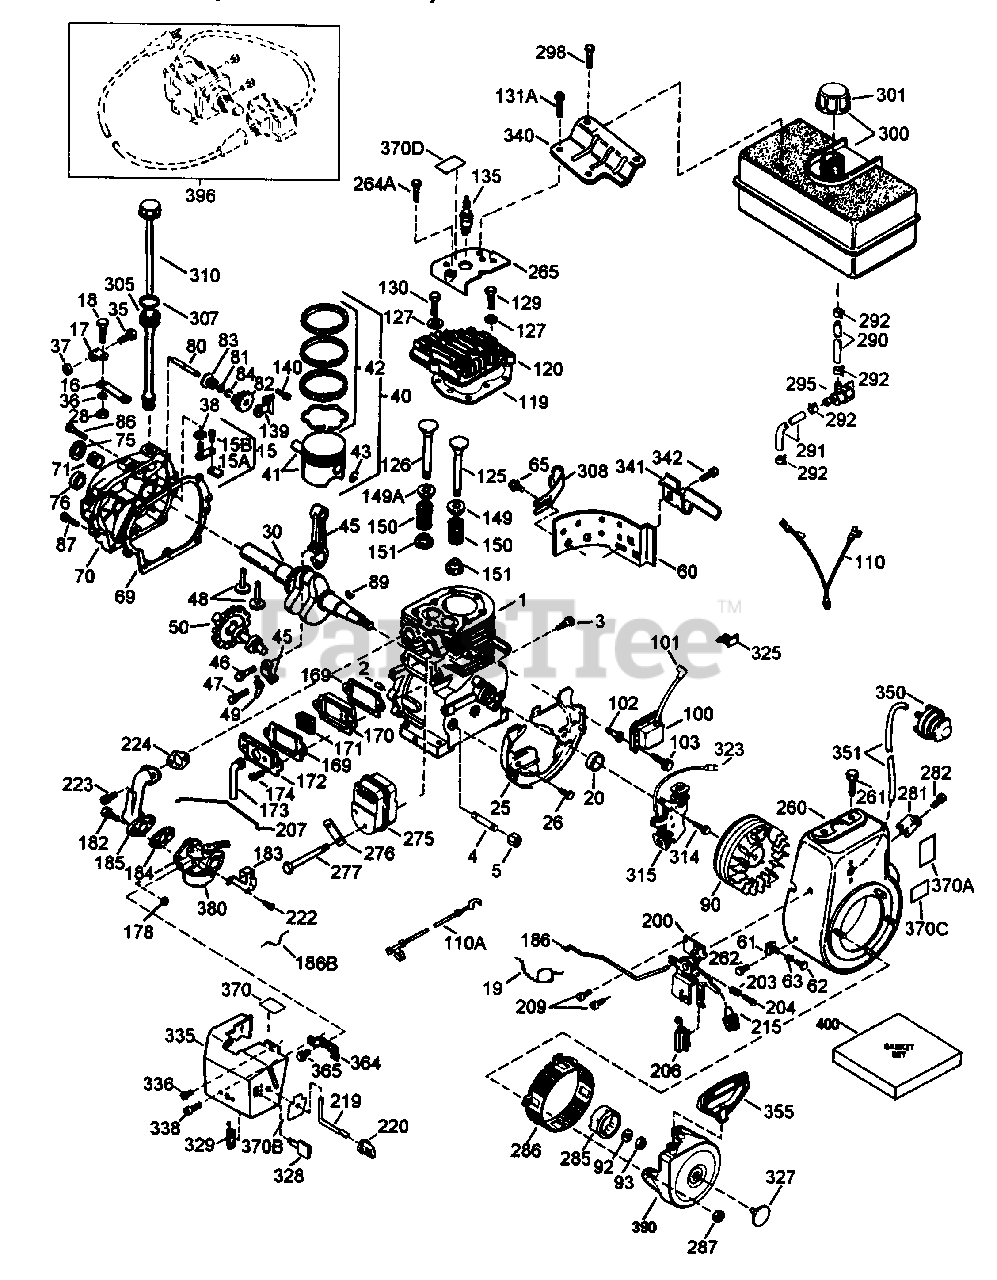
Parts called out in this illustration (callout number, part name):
1	Cylinder
2	Dowel Pin
3	Screw, 1/4-20 x 1/2"
4	Oil Drain Extension
5	Extension Cap
15	Governor Rod
15A	Governor Yoke
15B	Screw, 6-40 x 5/16"
16	Governor Lever
17	Governor Lever Clamp
18	Screw, 8-32 x 5/16"
19	Speed Control Spring
25	Blower Housing Baffle
26	Screw, 1/4-20 x 5/8"
28	Lock Nut, 8-32
30	Crankshaft
35	Screw, 10-32 x 3/4"
36	Lock Washer
37	Lock Nut, 10-32
38	Retaining Ring
40	Piston, Pin & Ring Set (Std.)
40	Piston, Pin & Ring Set (.010" OS)
40	Piston, Pin & Ring Set (.020" OS)
41	Piston 8 Pin Ass'y. (Std.)
41	Piston & Pin Ass'y. (.010" OS)
41	Piston 8 Pin Ass'y. (.020" OS)
42	Ring Set (Std.)
42	Ring Set (.010" OS)
42	Ring Set (.020" OS)
43	Piston Pin Retaining Ring
45	Connecting Rod Ass'y.
46	Connecting Rod Bolt
47	Connecting Rod Bolt
48	Valve Lifter
49	Oil Dipper
50	Camshaft (MCR)
60	Blower Housing Extension
61	Grommet Mounting Bracket
62	Screw, 8-32 x 3/8"
65	Screw, 10-24 x 1/2"
69	Cylinder Cover Gasket
70	Cylinder Cover
71	Crankshaft Bushing
76	Camshaft Seal
80	Governor Shaft
82	Governor Gear Ass'y.
83	Governor Spool
84	Retaining Ring
86	Screw, 1/4-20 x 1-3/16"
87	Screw, 1/4-20 x 1-11/16"
89	Flywheel Key
90	Flywheel (w/Ring Gear)
92	Lock Washer
93	Flywheel Nut
100	Solid State Ignition
101	Spark Plug Cover
102	Solid State Mounting Stud
103	Screw, Torx T-15, 10-24 x 15/16"
110	Ground Wire
110A	Ground Wire
119	Cylinder Head Gasket
120	Cylinder Head
125	Exhaust Valve (Std.)
125	Exhaust Valve (1/32" OS)
126	Intake Valve (Std.)
126	Intake Valve (1/32" OS)
129	Screw, 5/16-18 x 1-3/4"
130	Screw, 5/16-18 x 1-1/2"
131A	Screw, 5/16-18 x 5/8"
135	Resistor Spark Plug
139	Governor Gear Bracket
140	Screw, 10-24 x 1/2"
149	Valve Spring Cap
149A	Valve Spring Cap
150	Valve Spring
151	Valve Spring Keeper
169	Valve Cover Gasket
170	Breather Body
171	Breather Element
172	Valve Cover
173	Breather Tube
174	Screw, 10-24 x 1/2"
178	Nut and Lock Washer, 1/4-28
182	Screw, 1/4-28 x 1"
183	Choke Bracket
184	Carburetor To Intake Pipe Gasket
185	Intake Pipe
186	Governor Link
200	Control Bracket
203	Compression Spring
204	Screw, 5-40 x 7/16"
207	Throttle Link
209	Screw, 10-32 x 1/2"
215	Control Knob
219	Choke Rod
220	Choke Knob
222	Screw, 10-32 x 1/2"
223	Screw, Torx T-30, 5/16-18 x 1-1/8"
224	Intake Pipe Gasket
260	Blower Housing
261	Screw, 5/16-18 x 3/4"
262	Screw, Torx T-40, 5/16-24 x 21/32"
264A	Screw, 1/4-20 x 5/8"
265	Cylinder Head Cover
276	Locking Plate
277	Screw, 5/16-18 x 4-3/16"
281	Starter Bubble Cover
282	Screw, 8-32 x 3/8"
285	Starter Cup
286	Starter Screen
287	Nut 8 Lock Washer, 1/4-28
290	Fuel Line
291	Fuel Line
292	Fuel Line Clamp
295	Fuel Shut-Off Valve
298	Screw, 1/4-15 x 7/8"
300	Fuel Tank
301	Fuel Cap
305	Oil Fill Tube
308	Fill Tube Clip
314	Screw, 1/4-20 x 3/4"
315	Alternator Coil (18 Watt)
325	Wire Clip
327	Logo Decal
328	Ignition Key
335	Carburetor Cover
336	Screw, 10-32 x 1/2"
338	Screw, 10-32 x 3/8"
340	Fuel Tank Bracket
341	Fuel Tank Bracket
342	Screw, 1/4-20 x 5/8"
350	Primer Ass'y.
351	Primer Line
355	Starter Handle
364	Carburetor Cover Bracket
365	Screw, 8-32 x 27/64"
370	Instruction Decal
370A	Primer Decal
370B	Instruction Decal
370C	Warning Decal
370D	Lubrication Decal
380	Carburetor
390	Rewind Starter
396	Electric Starter Motor
400	Gasket Set
